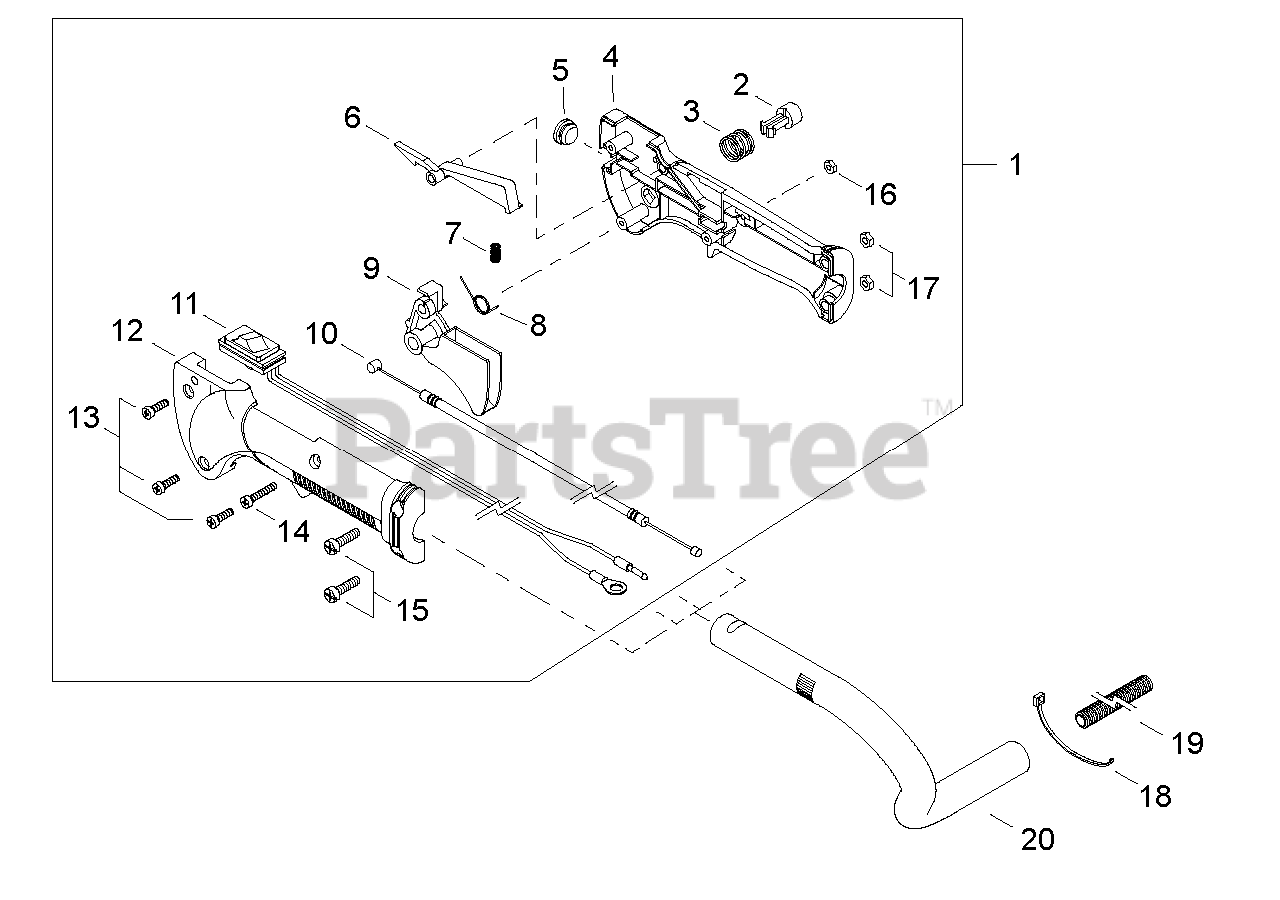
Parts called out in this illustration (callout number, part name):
1	THROTTLE CONTROL ASSY
2	LOCK, THROTTLE
4	HANDLE, CONTROL - RIGHT
6	LEVER, TRIGGER LOCKOUT
8	SPRING, TRIGGER
9	TRIGGER, THROTTLE
10	CABLE, THROTTLE
11	IGNITION SWITCH ASSY
12	HANDLE, CONTROL - LEFT
13	SCREW - 4X16 -- TAPPING
14	SCREW - 4X23
15	SCREW - 5X20
16	NUT - 4
17	NUT - 5
18	TIE, CABLE
19	TUBE, PROTECTIVE - CORRUGATED
20	HANDLE - REAR
